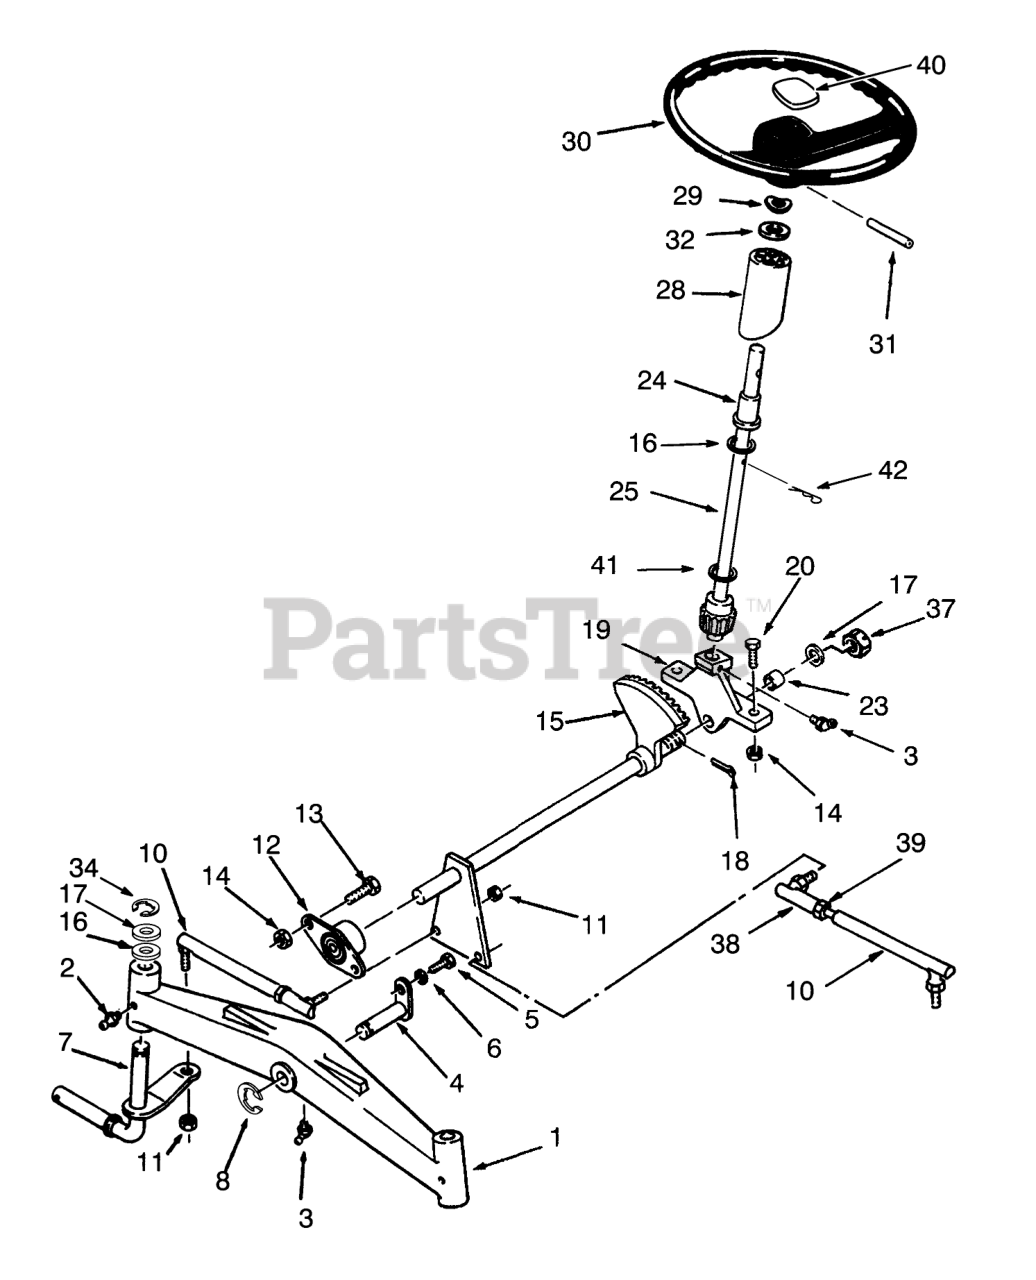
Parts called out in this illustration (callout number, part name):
1	AXLE-FRONT
2	FITTING-GREASE
3	FITTING-GREASE
4	PIN AND PLATE ASM
5	SCREW-HH
6	WASHER-LOCK
7	RH SPINDLE WA
8	E-RING
10	Tie Rod Assembly (Incl. Ref. #38 & 39)
11	NUT HEX 3/8-24 E.S.
12	BEARING-FLANGED
13	SCREW-HH
14	NUT-LOCK, NI
15	Shaft
16	WASHER-SHIM
17	WASHER
18	PIN-COTTER
19	Support-Steering
20	SCREW-HH
23	BEARING-BRONZE
24	BEARING-FLANGED
25	STEERING SHAFT ASM
28	TUBE-STEERING
29	WASHER-BOWED
30	Steering Wheel (Incl. Ref. #40)
31	PIN-ROLL
32	WASHER-FLAT
34	RING-RETAINING
37	NUT-HEX, SLOTTED
38	BALL-JOINT
39	NUT-6
40	STRG-WHL INSERT TORO
41	O-RING
42	PIN-COTTER
